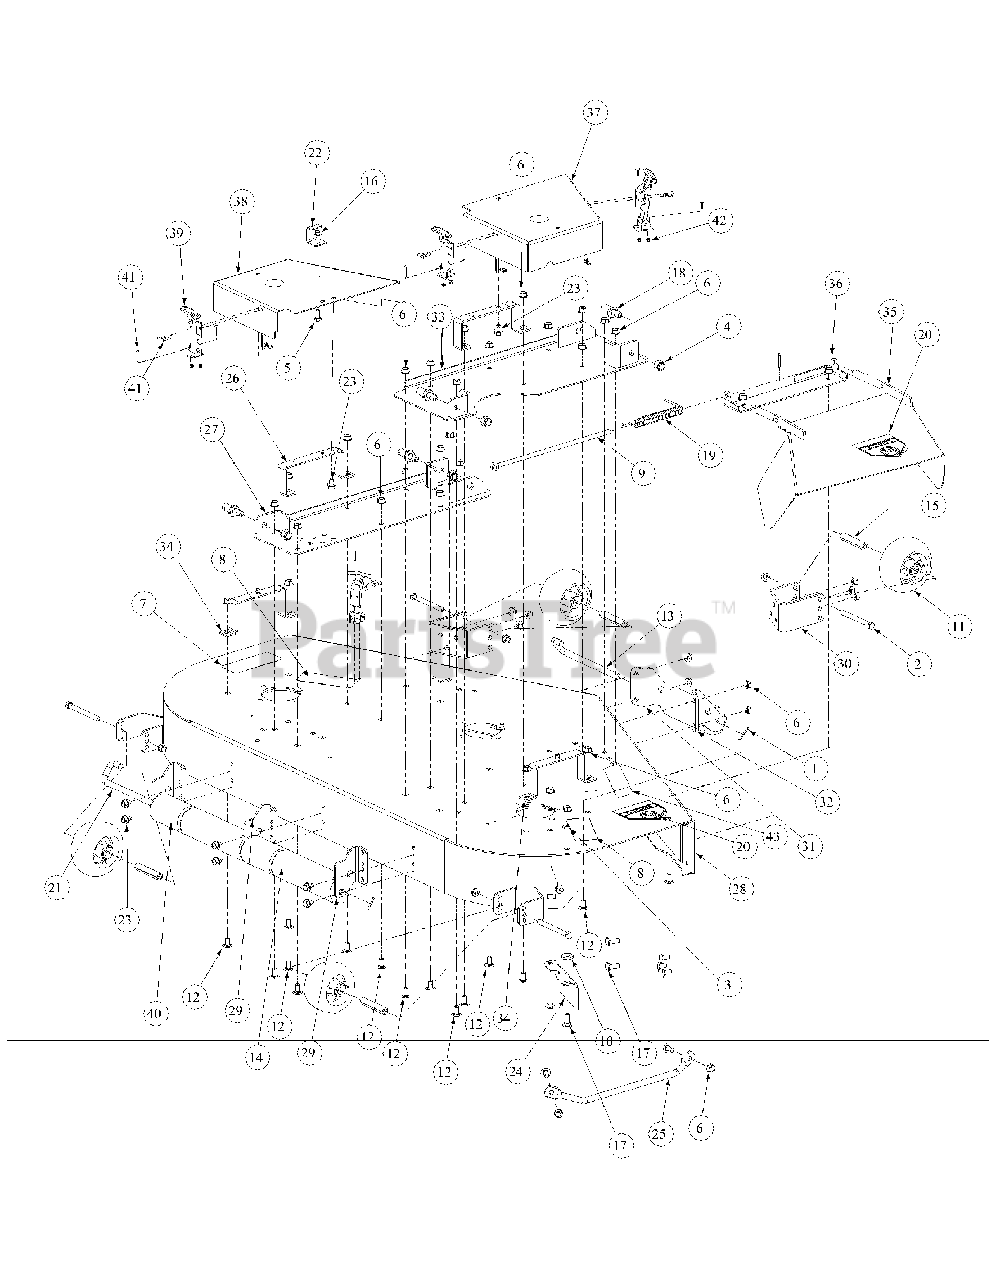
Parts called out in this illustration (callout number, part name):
1	Cotter Pin, .125 Dia. x 1.0
2	Hex Cap Screw, 3/8-16, 3.75
3	Flat Washer, 3/8
4	Lock Nut, Nylon Insert, 1/2-13
5	Hex Cap Screw, 5/16-18 x 3/4
6	Flange Lock Hex Nut, 3/8-16
7	Decal Rotating Blade
8	Decal Warning Shield Missing
9	Deflector Pivot Assembly, Pin
10	Idler Washer
11	Complete Wheel, 5.00 Dia
12	Carriage Bolt, 3/8-16 x .75 Lg
13	Roller Pin, 1/2 Dia x 7.31 Lg
14	Front Roller
15	Wheel Spacer
16	Hex Flange Lock Nut, 5/16-18
17	Carriage Bolt, 3/8-16 x 1
18	Pin, 5/8 Dia. x 1.2 Lg.
19	Torsion Spring
20	Decal, Danger Hands and Feet
21	Roller Rod
22	Bracket Stop Tension Rod
23	Hex Index Washer Screw, 3/8-16, .05
24	Fabricated Deck, Chute Bracket
25	Fabricated Deck Finger Guard
26	Fabricated Belt Support Cover
27	Left Hand Deck Bracket Assembly
28	48 Fabricated Deck Assembly
29	Fabricated Deck Roller Mount Bracket
30	Front Anti-Scalp Wheel Mount Bracket
33	Right Hand Deck Bracket Assembly
34	Outer Belt Cover Support Assembly
35	Chute Assembly
36	Deck Chute Mounting Bracket
37	Right Hand Belt Cover
38	Left Hand Belt Cover
39	Latch Drawing, T-Handle
41	Phillip Head Screw, 10-32
42	Lock Nut, Nylon Insert, 10-32
43	Mower Deck Label
